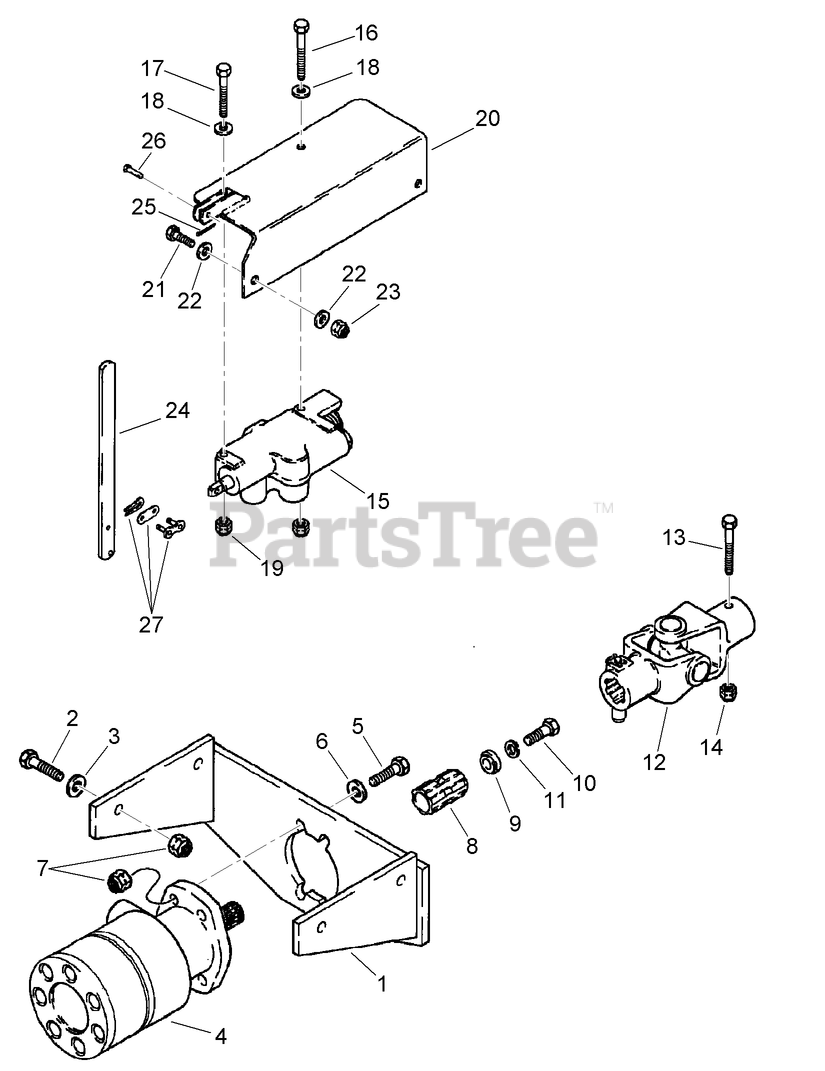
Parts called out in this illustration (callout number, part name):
1	MOUNT - Hydra-Borer Motor
2	BOLT-Hex Hd 1/2 x 1-3/4 GR5 ZND
3	WASHER-FLAT
4	HYD MOTOR ASM
5	BOLT-Hex Hd 1/2 x 1-3/4 GR5 ZND
6	WASHER-FLAT
7	NUT-HEX
8	ADAPTER
9	RETAINER-ADAPTER
10	BOLT-Hex Hd, 0.500 UNF x 1.25 GR5 ZND
11	WASHER-Spring Lock Reg 1/2 ZND
12	U-JOINT ASM
13	BOLT-hex, 3/8 NC x 2-1/2 inch, grade 2
14	NUT-HEX
15	SINGLE SPOOL VALVE ASM
17	BOLT-Hex Hd 5/16 x 2-1/4
18	WASHER-FLAT
19	NUT-HEX
20	BRACKET - Valve Mounting
21	SCREW-HH
22	WASHER-FLAT
23	NUT-HEX
24	LEVER-VALVE
25	PIN - Cotter .062 x .50 in ZND
26	PIN-CLEVIS
27	LINK-#50, CONNECT (SINGLE PITCH)
